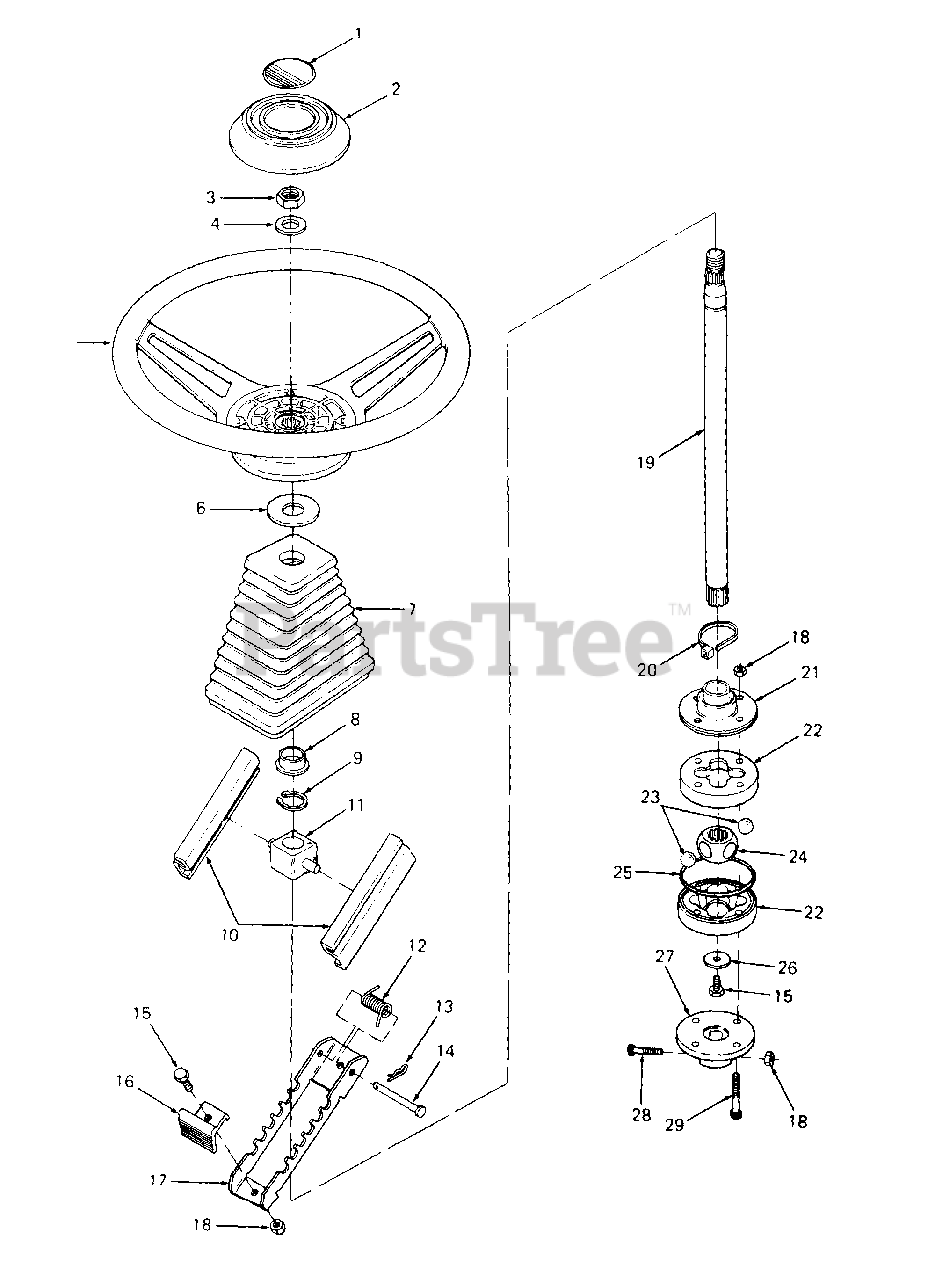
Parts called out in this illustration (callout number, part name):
1	Label, Steering Cap
2	Cap, Steering Wheel
3	Nut, Hex Jam, 5/8-18
4	Washer, Flat, .640 X 1.24 X.06 Thk HDN
6	Washer, Flat, .755 X 2.0 X.030 Thk
7	Boot, Steering Shaft
8	Bearing, Flange
9	Ring, Snap
11	Bushing, Shaft Guide
12	Spring-Tilt, Torsion
13	Pin, Internal Cotter
14	Pin, Clevis, .25 Dia X 2.38 Lg
15	Screw, Hex Cap, 1/4-20 X.50 Lg GR5
16	Button, Tilt Control
17	Plate, Tilt Control
18	Nut, Hex Patch Lock, 1/4-20
19	Shaft, Upper Steering, 18.25 Lg
20	Strap, Tie
21	Boot, Coupling
22	Coupling, Drive w/0-Ring Groove
23	Ball, Steel, 5/8 Dia Chrome
24	Hub, Drive
25	O-Ring, 2.489 X.070
26	Washer, Flat, .265 X 1.0 X .030 Thk HDN
27	Adapter, Steering
28	Screw, Socket Hd Cap, 1/4-20 X 1.12 Lg
29	Screw, Socket Hd Cap, 1/4-20 X 1.75 Lg
